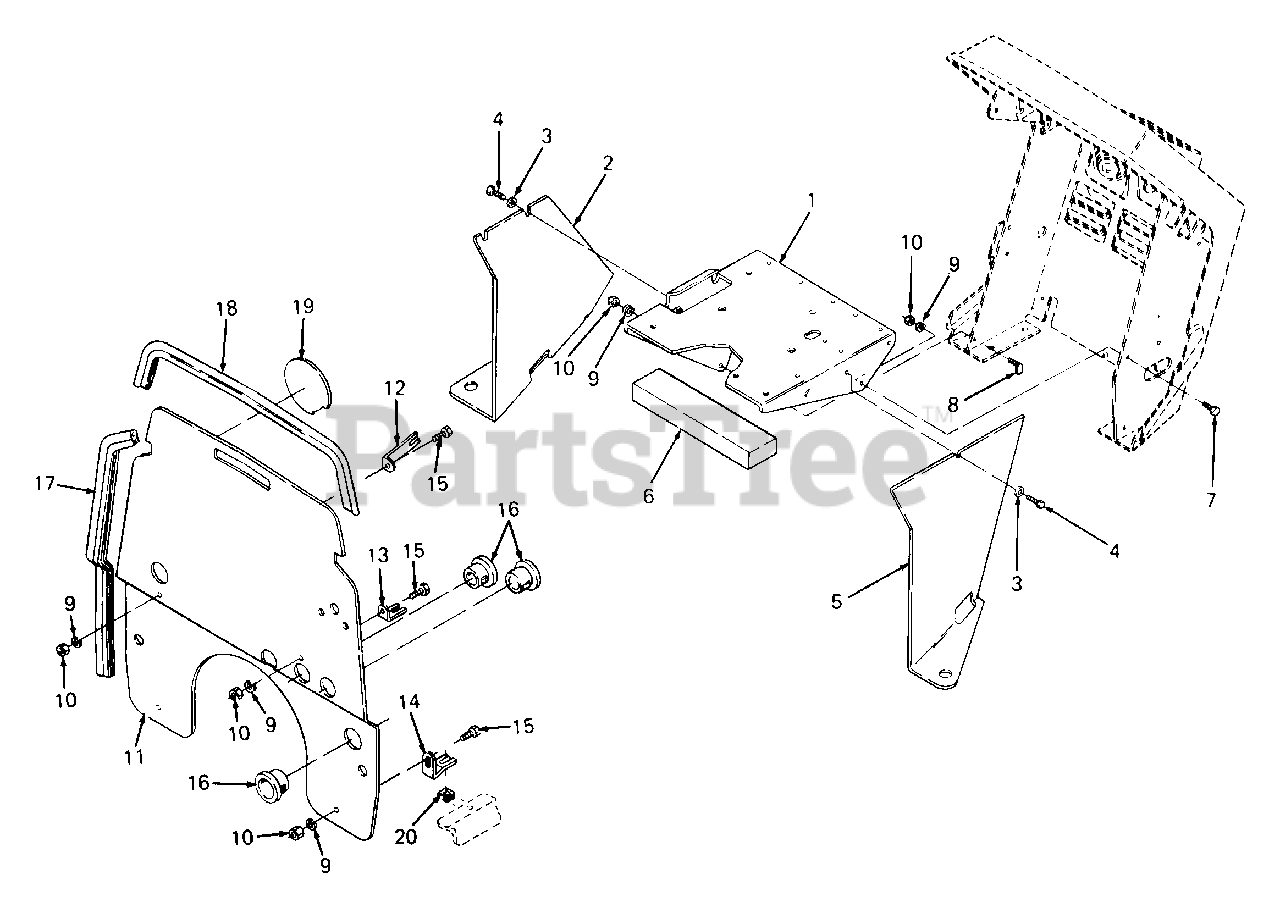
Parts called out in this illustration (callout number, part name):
1	Tray Assy, Battery
2	Baffle, Intake - RH
3	Washer, Bell, .380 X .88 X .060 Thk
4	Screw, Hex Cap, 5/16-18 X 1.0 Lg GR5
5	Baffle, Intake - LH
6	Strip, Foam Gasket Sealing, 10.31 Lg
7	Screw, Hex Cap, 1/4-20 X .62 Lg GR5
8	Bolt, J-Type, 1/4-20
9	Washer, Lock, 1/4
10	Nut, Hex, 1/4-20 GR5
11	Baffle, Heat
12	L-Bracket, 1.9 Lg
13	L-Bracket, 1.1 Lg
14	L-Bracket
15	Screw, Hex Cap, 1/4-20 X .5 GR5
16	Bushing, Snap, 7/8 ID
17	Seal, Heat Baffle, 19" Lg
18	Seal, Heat Baffle, 17" Lg
19	Insulator, "+" Battery Post
20	Nut, U-Type, 5/16-18
